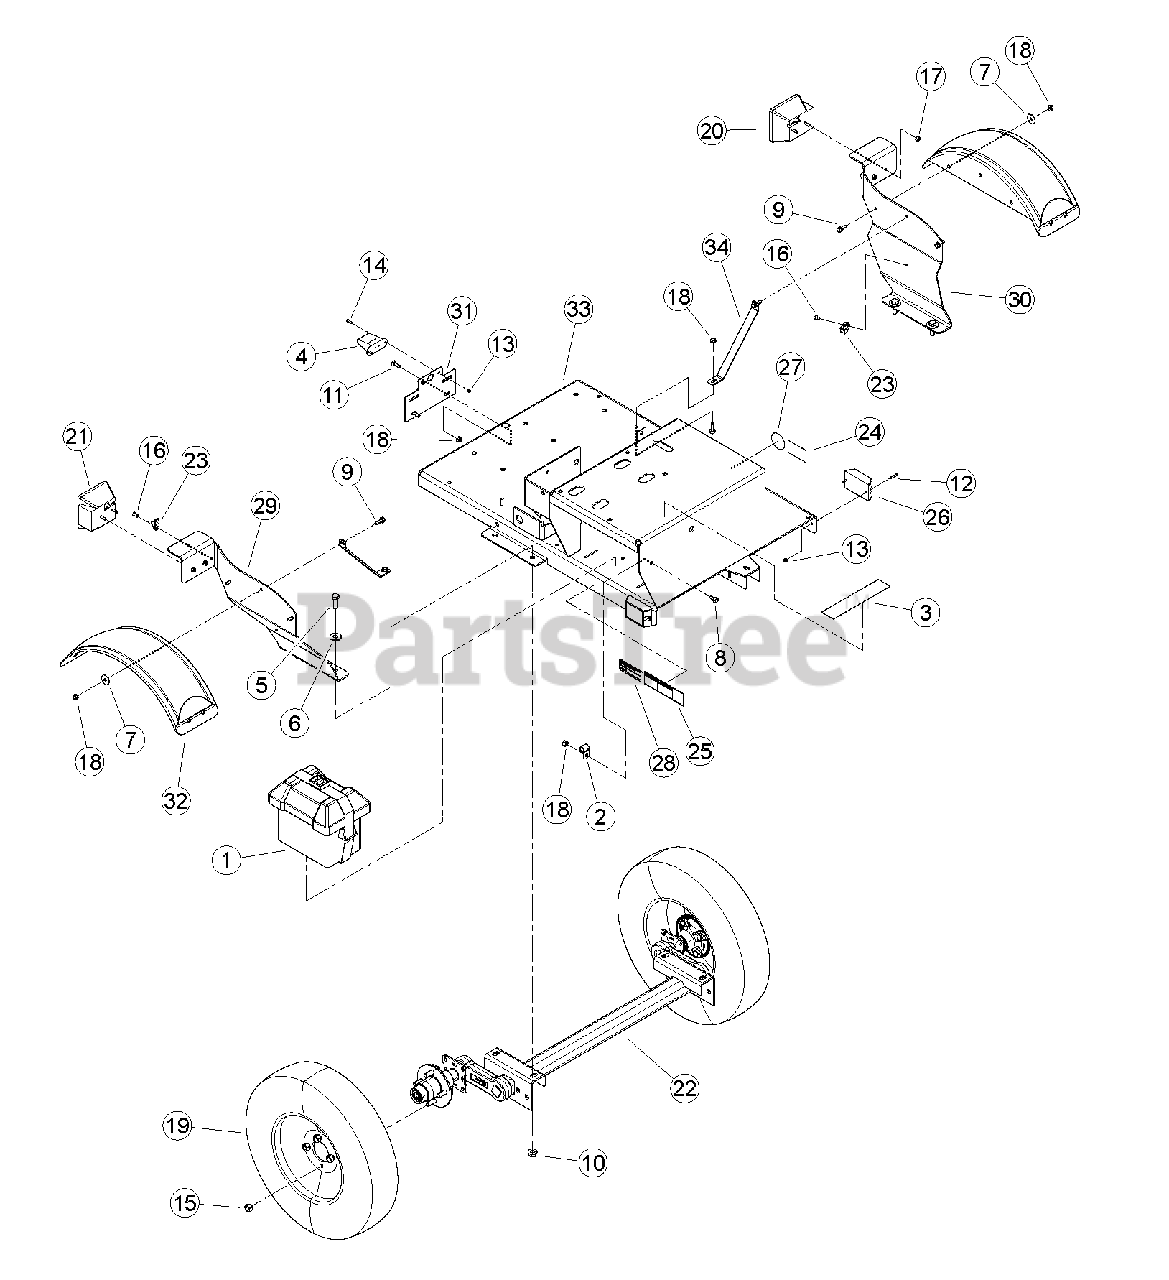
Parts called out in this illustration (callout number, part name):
1	BOX, SMALL BATTERY
2	CLAMP, 9/16 COATED
3	DECAL, CHIPPER ENGAGEMENT
4	LIGHT, LICENSE PLATE
5	BOLT, 1/2 X 1-1/2 HEX HD GR5 ZP
6	WASHER, 1/2" FLAT ZP
7	WASHER, 5/16" FENDER ZP
8	BOLT, 5/16 X 3/4 FLANGE NC
9	BOLT, 5/16 X 1 FLANGE NC
10	NUT, 1/2-13 NYLOCK FLANGE
11	BOLT, 5/16 X 1" GR5 CRG ZP
12	SCREW, MCH 10-24 X 1" RND HD PHL ZP
13	NUT, 10/24 NYLOCK TYPE NM, ZP
14	SCREW, MCH #10-24 X 3/4" PAN HD PH ZP
15	NUT, 1/2-20 WHEEL
16	RIVET, AL BLIND 1/4 X 3/4 DOME HEAD
17	NUT, 1/4-20 NYLOCK-FLANGE
18	NUT, 5/16-18 NYLOCK-FLANGE
19	ASSEMBLY, 5.30-12 TIRE + SPOKE RIM
20	LIGHT, LH TAIL
21	LIGHT, RH TAIL
22	AXLE, 1000LB TORSION
23	CLAMP, CABLE MOUNT
24	DECAL, 5.30-12 LOAD RATING
25	DECAL, CHECK WHEELS
26	LIGHT, AMBER MARKER
27	DECAL, NATM COMPLIANCE
28	DECAL, EPA EVAP
29	BRACKET, RH FENDER
30	BRACKET, LH FENDER
31	PLATE, LICENSE
32	FENDER, BLACK PLASTIC DRILLED
33	WELDMENT, C/S TRAILER
34	BRACE, FENDER
